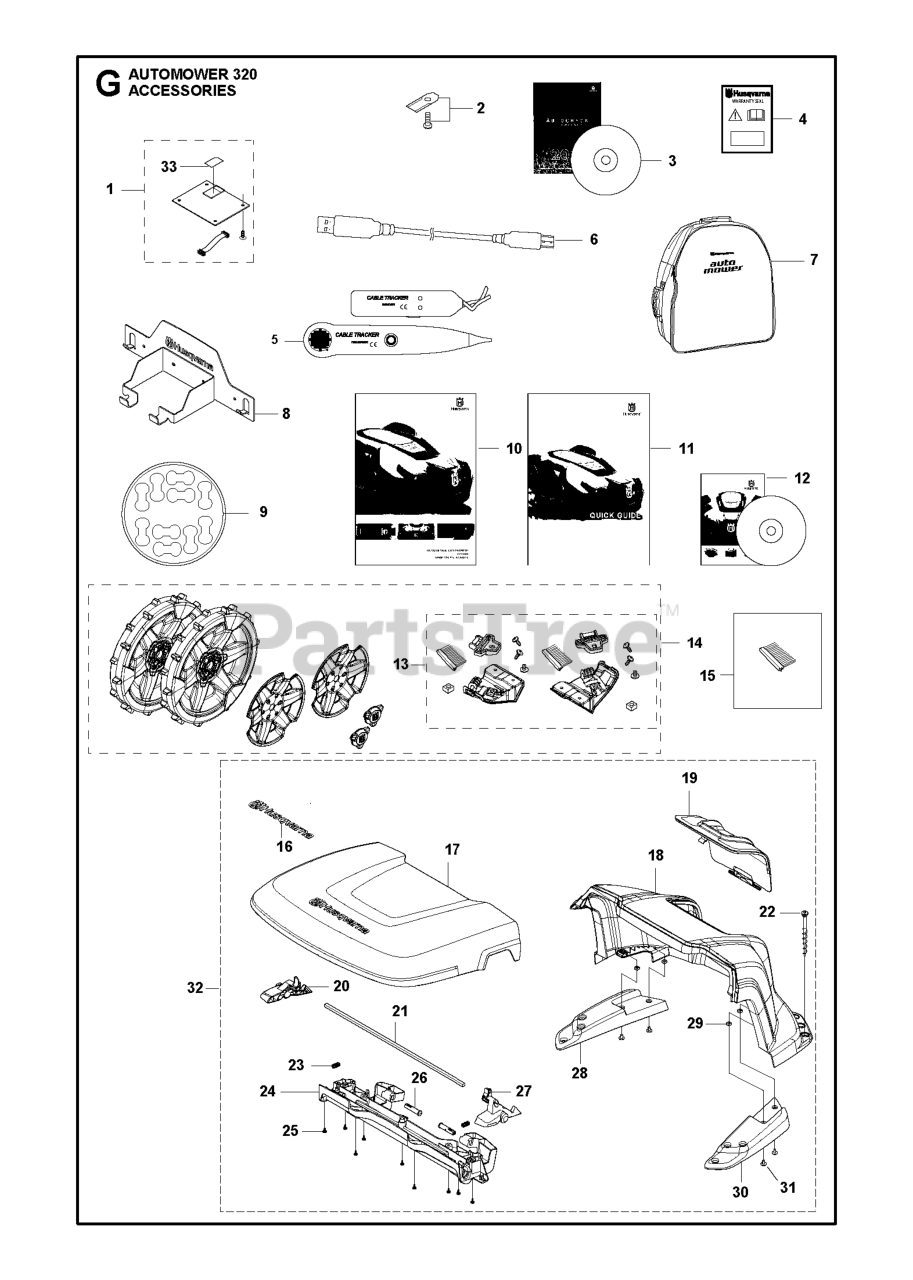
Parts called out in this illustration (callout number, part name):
2	STAPLE 100 PCS, BLISTER
2	STAPLE 100 PCS
3	SCREW 3 PCS, BLISTER PACK
4	CABLE ASSY LOW VOLTAGE CABLE
5	CABLE ASSY LOW VOLTAGE CABLE
6	CABLE ASSY LOW VOLTAGE CABLE
7	WIRE BOUNDARY 150M
7	WIRE 150M, BLISTER
8	WIRE 250M
9	WIRE 500M
10	BRAKER
10	CONNECTOR 5 PCS, BLISTER
11	SPLICE KIT
11	COUPLER SPLICER, 5 PCS,
11	COUPLER SPLICER, 100 PCS
12	RULER / CENTIMETERS
13	LABEL SECURITY
